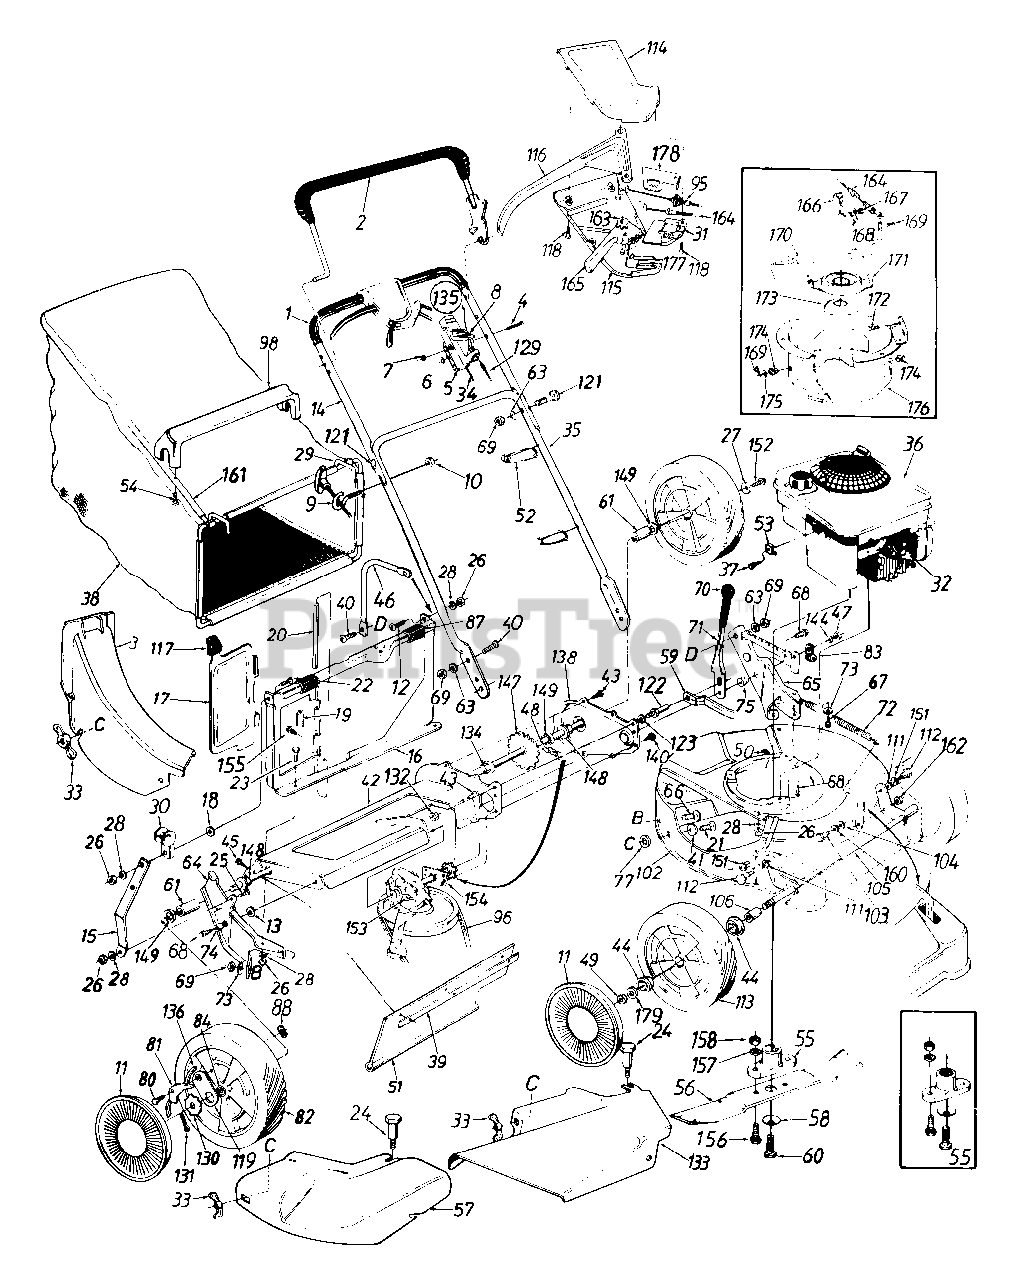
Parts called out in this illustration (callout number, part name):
1	Foam Grip
2	Control Handle Ass'y.
3	Rear Discharge Chute Ass'y.
4	Oval C-Sunk Scr.
5	Throttle Body
6	Spr. Wash..66" I.D.
7	Hex L-Nut 1/4-20 Thd.
8	Throttle Lever
9	Rope Guide Bolt
10	Hex L-Nut 1/4-20 Thd.
11	Hub Cap
12	Truss Mach. Scr. 1/4-20 x .62" Lg.
13	Fl-Wash..383" I.D. x 1" O.D.
19	Torsion Spring
20	Pivot Pin
21	Carriage Bolt 1/4-20 x .62"
22	Truss Mach. Scr. 1/4-20 x 3/4" Lg.
23	Hex Bolt 1/4-20 x .50" Lg.
24	Shoulder Bolt .312 Dia. x .18 Lg.
25	Hex Bolt 1/4-20 x .62" Lg.
26	Hex Nut 1/4-20 Thd.
27	Bell-Wash. 1/4" I.D.
28	L-Wash. 1/4" I.D.
30	Rope Guide
31	S.P. Control Cover
32	Spark Plug Insulator
33	Wing Nut w/Washer
34	Throttle Control Wire 61"
35	Lower Handle - Painted
36	Engine
37	Hex Self-Tap Scr. #10-32 x .62" Lg.
38	Grass Bag
39	Retaining Strip
40	Truss Mach. Scr. 5/16-18 x .75" Lg.
41	Fl-Wash..344" I.D. x .62"
44	Flange Ball Bearing 1/2" I.D.
45	Hex AB-Tap Scr. 1/4 x .62"
46	Catcher Panel Support Arm
47	Hex Patch L-Nut 3/8-24 Thd.
48	#48 Chain .500" Pitch x 30 Links
49	Hex Ins. Top L-Nut 3/8-16 Thd.
51	Rear Flap 3.75" x 17.30" Lg.
52	Cable Tie
53	Cable Clamp
54	Hex AB Scr. #12 x 1.25" Lg.
55	Blade Adapter Kit
56	21" Mulching Blade
57	Mulching Plug
58	Bell-Wash..46" I.D
59	Height Adj. Connecting Arm
60	Hex Bolt 7/16-20 x 1.5" Lg. (Grade 5)
61	Spacer .513" I.D. x .703" O.D. x .69" Lg
63	L-Wash. 5/16" I.D.
64	R.H. Handle Wheel Brkt. Ass'y.
65	L.H. Handle Wheel Brkt. Ass'y.
66	Carriage Bolt 5/16-18 x .62"
67	Hex Wash. Hd. B-Tap Scr. 5/16-18
68	Hex Wash. Hd. TT-Tap Scr. 3/8-16
69	Hex Nut 5/16-18 Thd.
71	Height Adj. Lever
72	Extension Spring .75" O.D. x 8" Lg.
73	Bell-Wash. 5/16" I.D.
74	Spacer
75	Shld. Spacer .500" Dia.
77	Bolt Retainer 1/4 x .50" O.D.
80	Shld. Scr..342" Dia. x .268
81	Pawl
82	Wheel Ass'y. Comp. (Gray)
83	Clamp
84	Bearing 1/2" I.D.
87	Panel Clip
88	Weld L-Nut 1/4-20 Thd.
95	S.P. Cable
96	"V"-Belt
98	Bag Handle
102	21" Deck Ass'y.
103	Shld. Bolt .5" Dia. x .295
104	Bell-Wash..515" I.D. x 1.0" O.D.
105	Front Axle Ass'y.
106	Sleeve .526" I.D. x .690" O.D. x .880" Lg.
111	Intern. L-Wash. 3/8 I.D.
112	Shld. Bolt .575" Dia. x .42
113	Wheel Ass'y. Comp. (Gray)
114	Self-Propelled Control Cover
115	Self-Propelled Control Cover
116	Control Lever
117	Door Grip
118	Fl-"C"-Sunk Hd. Tap Scr. #10 x .75" Lg.
119	Pawl Plate
121	Curved Carr. Bolt 5/16-18 x 1.38" Lg
122	Shld. Pin 3/8-24 x 1.43" Lg.
123	L-Wash. 3/8" I.D.
129	Control Cable 47" Lg.
130	Ratchet Wheel 1.62" O.D.
131	Cotter Pin 1/8" Dia. x 1.00" Lg.
132	Hex Jam Nut 3/8-24 Thd.
133	Side Chute Deflector Ass'y.
134	Hex Flange Bearing
135	Throttle Box Comp.
136	Spring - Nylon
144	Fl-Wash..385" I.D. x .87"
147	Rear Shaft Ass'y. 21.94" Lg.
148	Hex Flange Bearing .506" I.D. Plastic
149	Fl-Wash..531" I.D. x.930"
151	Flanged Nyliner Brg.
152	Hex Bolt 1/4-20 x .62" Lg. (Grade 5)
153	Transmission Comp. (See Breakdown)
154	Hex Bearing Cup
155	Hex B-Tap Scr. #10 x .38
156	Hex Scr. 3/8-24 x 1.0" Lg.
157	L-Wash. 3/8" I.D.
158	Hex Nut 3/8-24 Thd.
160	Fl-Wash..51" I.D. x .75" O.D.
162	Hex Jam Nut 3/8-16 Thd.
163	3 Tooth Rack Gear Insert
164	Spd. Control Cable - 50" Lg.
165	6-Spd. Shift Lever
168	Hex Cent. L-Nut 1/4-20 Thd.
169	Cot-Pin 3/32" Dia. x .75" Lg.
170	Shift Rod
171	Movable Pulley Half Ass'y.
172	Carr. Bolt 1/4-20 x .50" Lg.
173	Spined Pulley Half
174	Flanged Bushing
175	Fl-Wash..328" I.D. x .68" O.D.
176	Cable Mtg. Brkt. Ass'y.
177	Shift Lever Spring
178	6-Speed Rack Cable Brkt.
179	Fl-Wash. .385" I.D. x .87" O.D.
17055B-0637	AXLE ASSY-CHAIN - POWDER BLACK (0637)
17055B-0638	AXLE ASSY-CHAIN - MTD/TROY-BILT RED (0638)
17055B-0665	AXLE ASSY-CHAIN - YARDMAN GREEN (0665)
